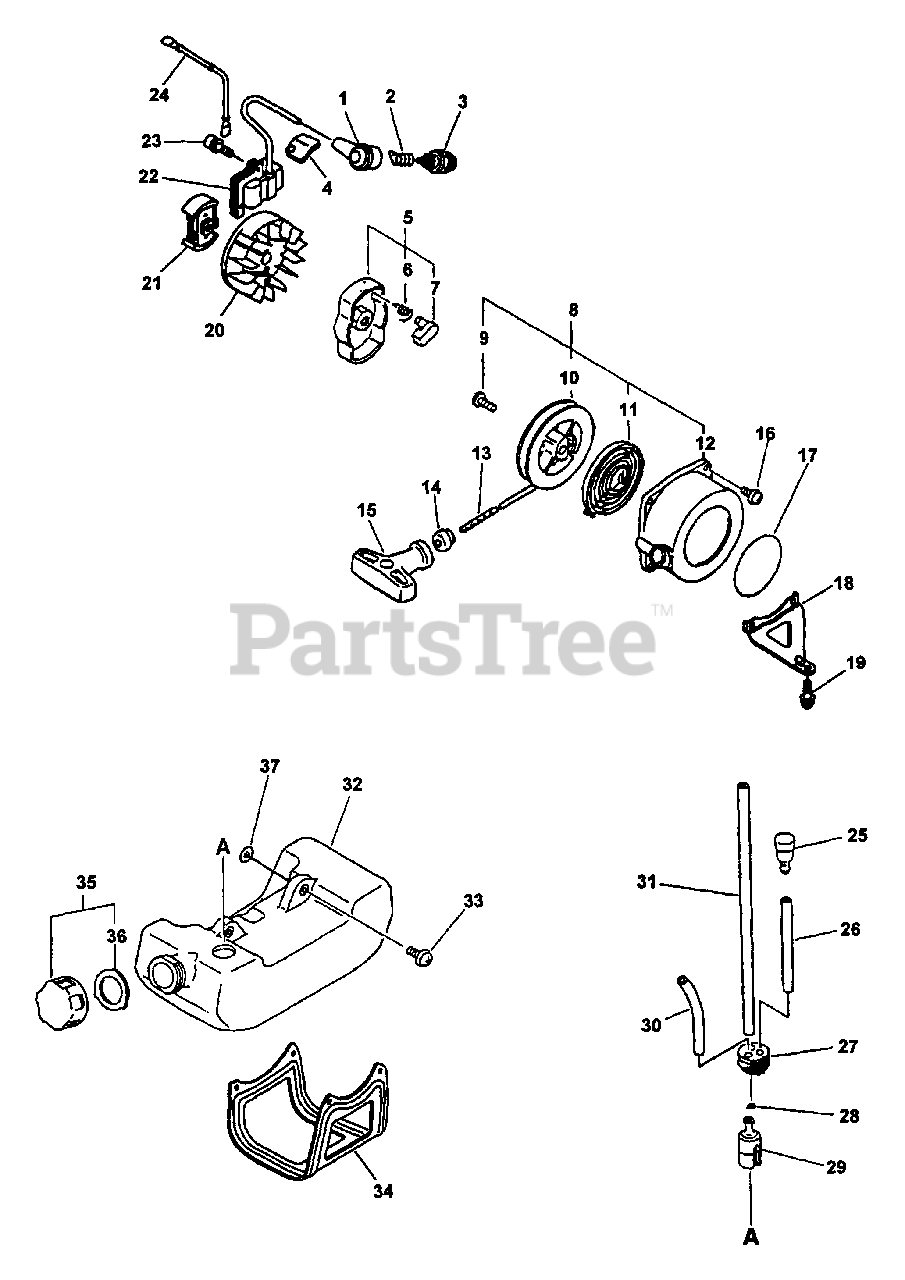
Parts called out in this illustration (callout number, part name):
1	CAP, SPARK PLUG
2	TERMINAL, SPARK PLUG
3	SPARK PLUG - BPM-7Y
5	PAWL ASSY, STARTER
6	SPRING, RETURN
7	PAWL, STARTER - BLACK
8	STARTER ASSY, RECOIL
9	SCREW
10	REEL, ROPE
11	SPRING, RECOIL
12	CASE, RECOIL STARTER
13	ROPE, STARTER
14	GUIDE, ROPE
15	GRIP, STARTER
16	BOLT 4×16
17	LABEL - ECHO
18	SUPPORT, HANDLE
19	SCREW 5×16
21	CLUTCH ASSY
22	COIL, IGNITION
23	SCREW 4×22
24	LEAD
25	VENT ASSY
26	PIPE, VENT
27	GROMMET, FUEL
28	CLIP 6 MM
29	FILTER, FUEL
30	PIPE, FUEL 3×6×80 CLEAR
31	PIPE, FUEL
32	TANK, FUEL
33	SCREW 5×16
34	GUARD, FUEL TANK
35	CAP ASSY, FUEL
36	GASKET, FUEL CAP
37	WASHER 5.5×12×0.8
